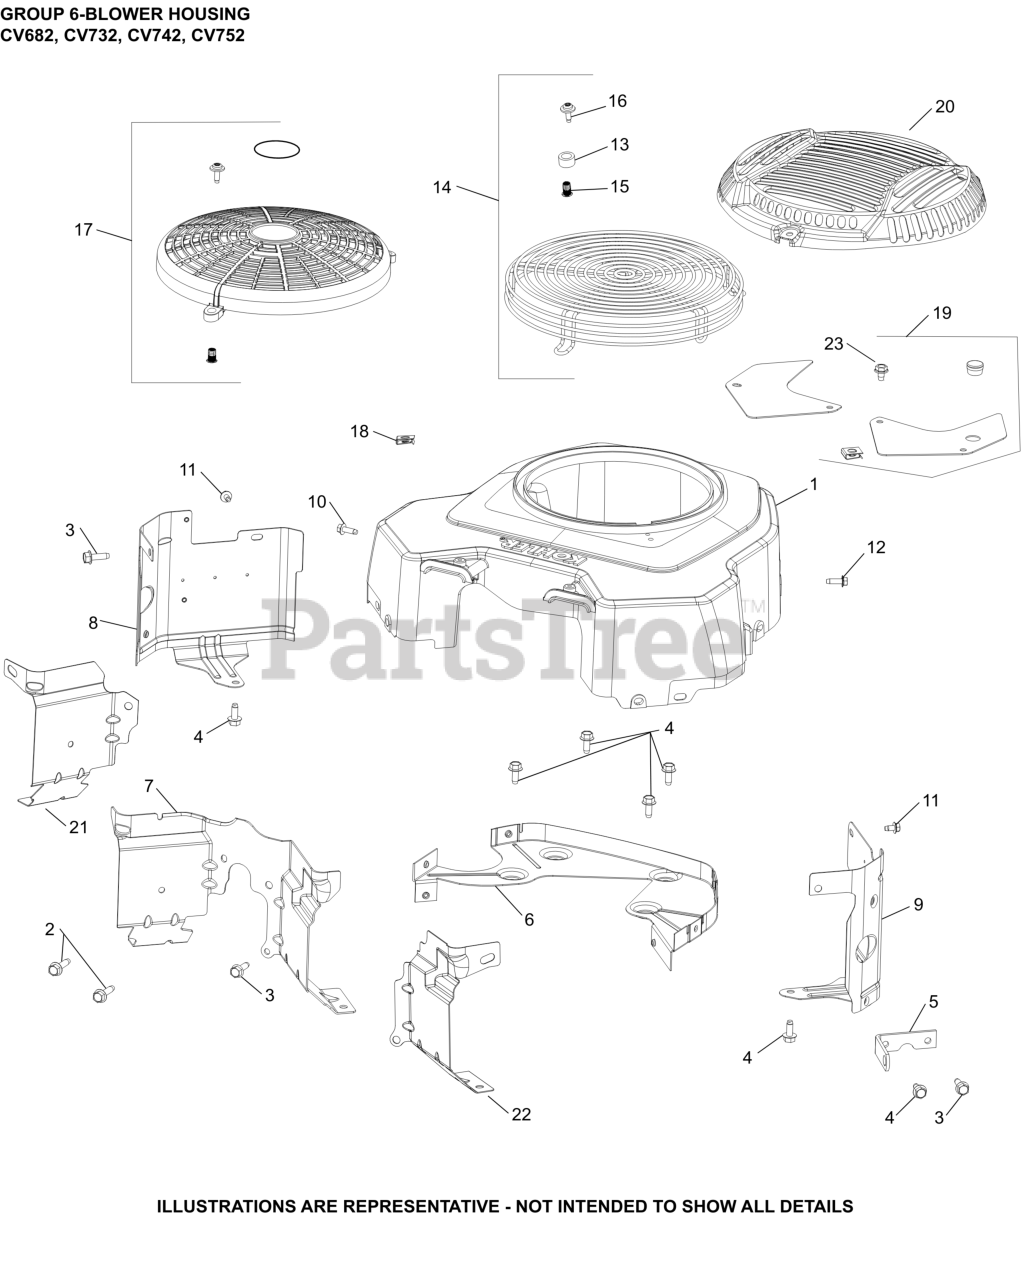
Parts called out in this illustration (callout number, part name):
1	KIT, BLOWER HOUSING
4	SCREW, THREAD FORMING
6	KIT, BACKING PLATE
8	KIT, CYL BAFFEL #1 SIDE
9	BAFFLE, LEFT BARREL
10	SCREW, THREAD FORMING
11	SCREW, THREAD FORMING
12	SCREW, THREAD FORMING
14	INSERT, THREADED (M5)
16	SCREW, SEMS
20	GUARD, GRASS SCREEN (METAL)
21	BAFFLE, VALLEY #1 CYLINDER
22	BAFFLE, VALLEY #2 CYLINDER
NI	STRAP, LIFTING
